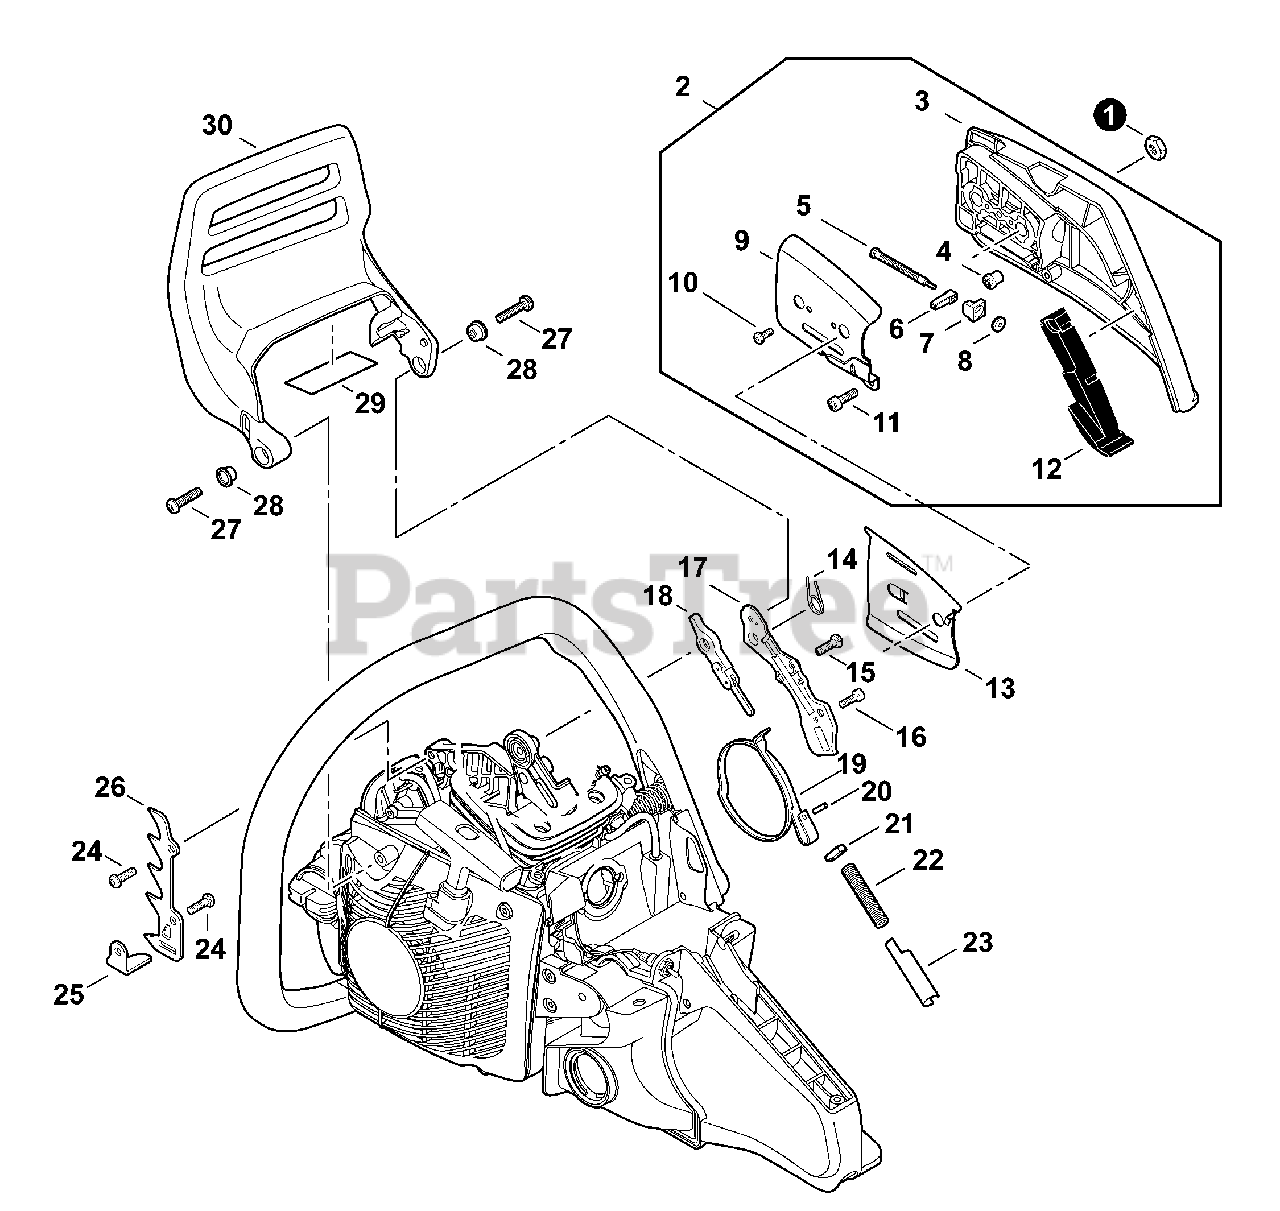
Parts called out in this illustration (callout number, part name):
2	GUARD KIT, SPROCKET
3	GUARD, SPROCKET
4	GEAR, BEVEL
5	SCREW, CHAIN TENSION 63 MM
6	TENSIONER, CHAIN
7	COLLAR 8
8	GEAR, BEVEL
9	PLATE, GUIDE - OUTER
10	SCREW 3×6
11	BOLT, TORX 4×12
12	CUSHION
13	PLATE, GUIDE - INNER
14	SPRING, TORSION
15	BOLT, TORX 5×16
16	BOLT, TORX 4×12
17	COVER, BRAKE
18	CONNECTOR, BRAKE
19	BAND, BRAKE
20	PIN, SPRING 3×9.8
22	SPRING, COMPRESSION 12×70.5
23	PLATE, SIDE
24	BOLT, TORX 5×16
25	CHAIN CATCHER
26	SPIKE, BUMPER
27	BOLT, TORX 5×16
28	COLLAR 11.2×16.2×T0.6
29	SHIELD, HEAT 75×27×0.15
30	LEVER, BRAKE
